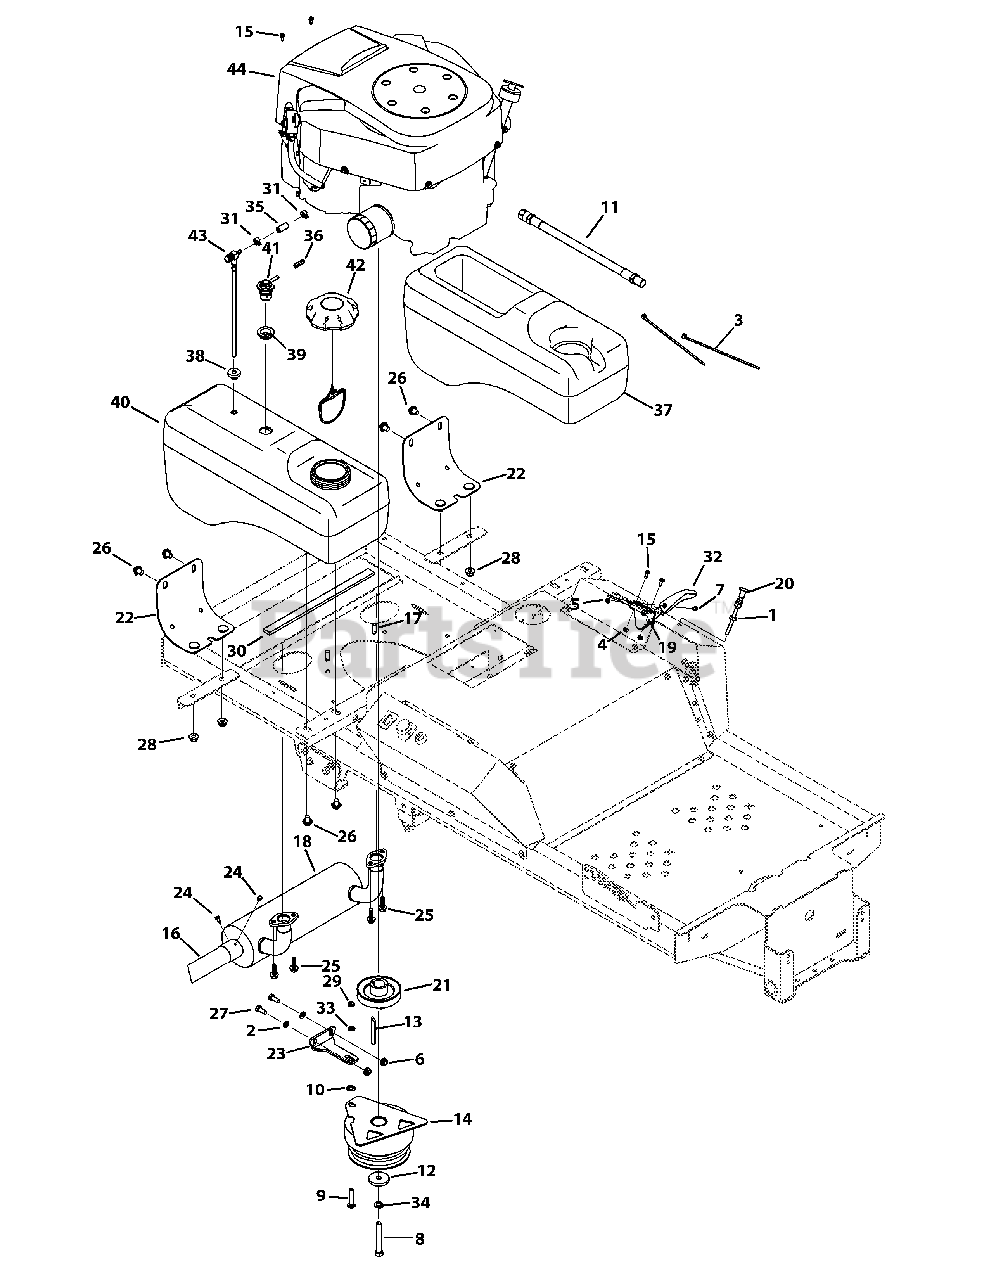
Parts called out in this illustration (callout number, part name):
1	Jam Nut, 3/8-24
2	Washer, 344 x .688 x .063
3	Cable Tie
4	Nylock Nut, #10-32
5	Nut, #8-32
6	Flange Counter Lock Nut, 5/16-18
7	Machine Screw, #8-32 x .356
8	Hex Screw, 7/16-20 x 3.00
9	Carriage Bolt, 5/16-18 x 1.75
10	Washer, .406 x .750 x .063
11	Oil Drain Hose
12	Washer, .438 x 1.745 x .250
13	Bevel Key, .250 x .250 x 2.75
14	PTO
15	Screw, #10-32 x .500
16	Straight Exhaust Pipe
17	Flange Screw, 3/8-16 x .875
18	Kohler Muffler
19	Throttle Control Cable
20	Choke Cable
21	Transmission Pulley
22	Fuel Tank Mounting Bracket Assembly
24	Hex Washer Screw, #10-16 x .500
25	Hex Flange Screw, 5/16-18 x 1.0
26	Hex Flange Screw, M10-1.5 x .500 x 8.8
27	Hex Screw, 5/16-18 x .75
28	Flange Lock Nut, 3/8-16
29	Jam Nut, 5/16-18
30	Foam Tape .75 x 25
31	Hose Clamp, .490
32	Throttle Control Knob
33	Lock Washer, 5/16
34	Lock Washer, 7/16
35	Low Permeation Fuel Hose, 1/4
36	Mono Vent Hose, 3/16
37	Utility Bin
38	Fuel Tank Bushing
39	Rubber Grommet, 23.0 x 3.55
40	Fuel Tank
41	Fuel Rollover Valve
42	Fuel Cap
43	Fuel Pick-Up Fitting (On/Off)
44	Engine SV840-3021
